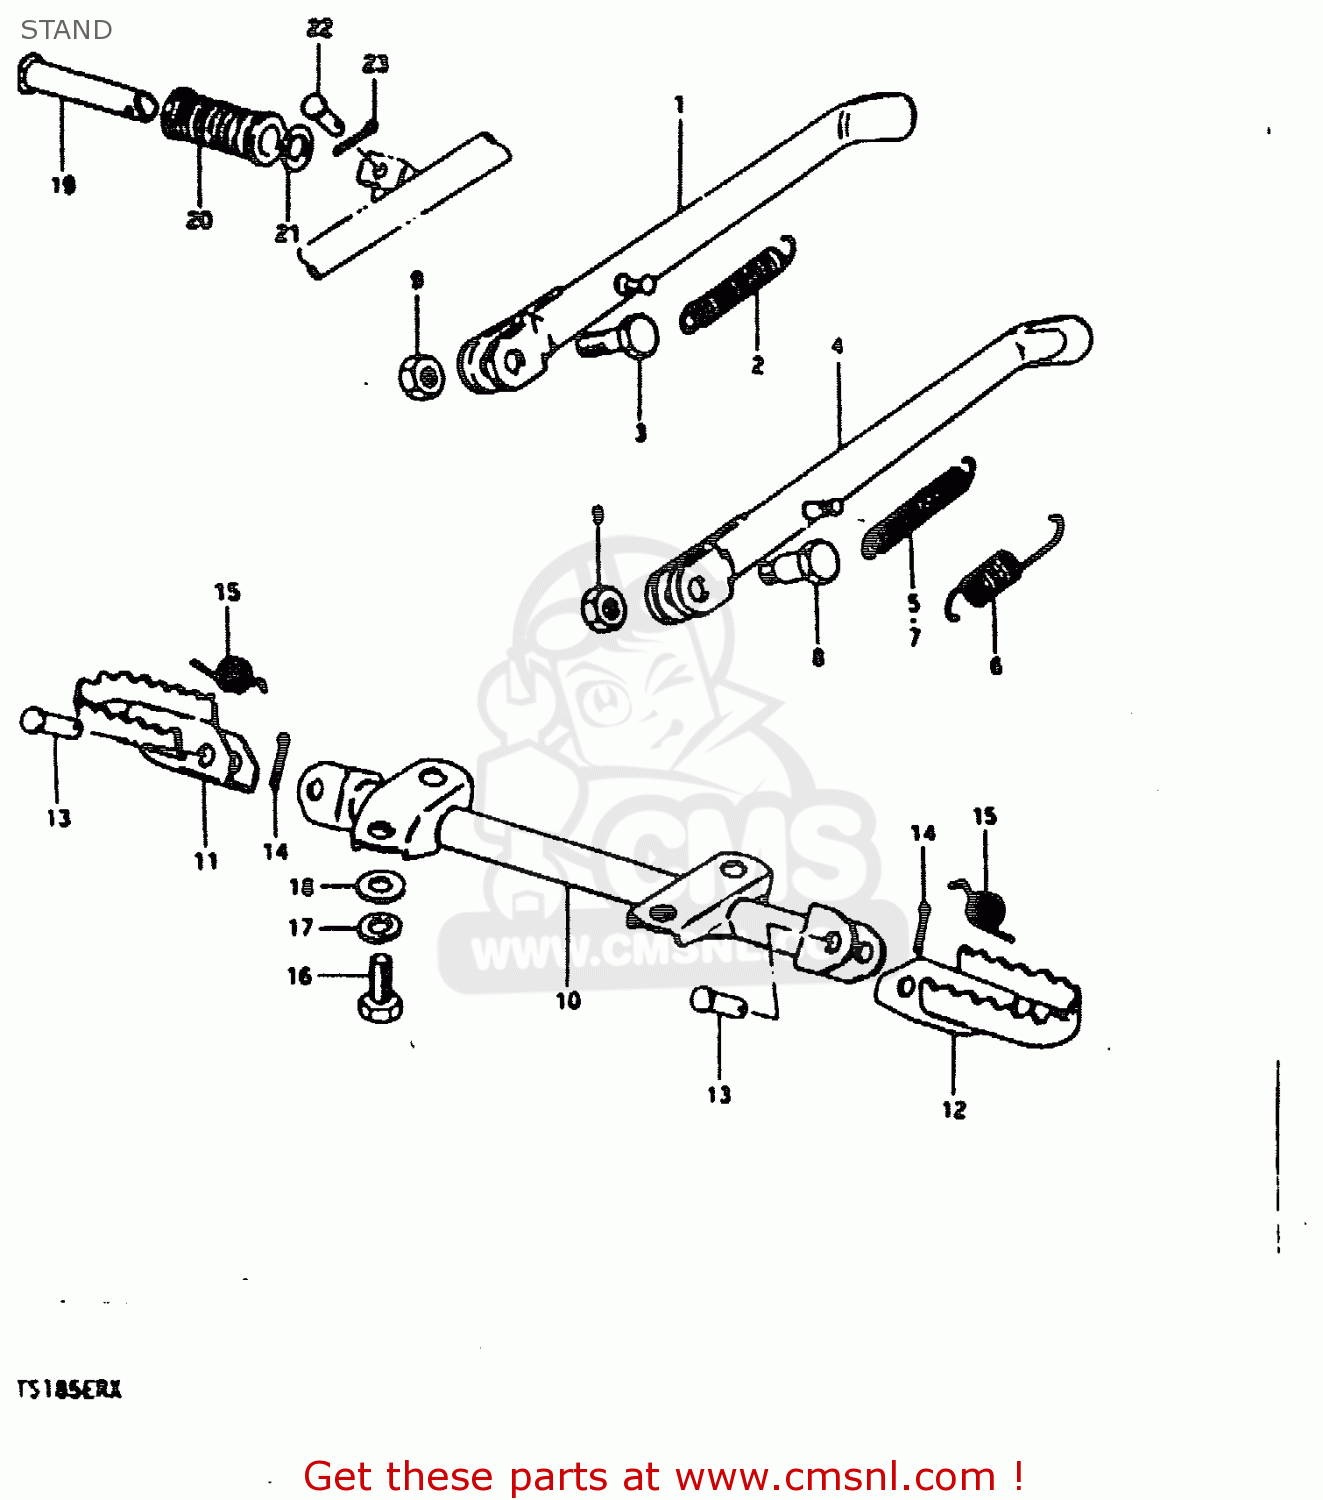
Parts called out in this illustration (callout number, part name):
1	STAND,PROP
2	SPRING
3	BOLT(10X30)
9	NUT
10	BAR,FR FOOTREST
11	FOOTREST,FR,R
12	FOOTREST,FR,L
13	PIN
14	PIN 20X20
15	SPRING
16	BOLT
17	WASHER,LOCK,8.
18	WASHER
19	BAR,FOOTREST RUBBER
20	RUBBER,PILLION FOOTREST
21	WASHER (19.5X32X2)
22	PIN
23	PIN 20X20
